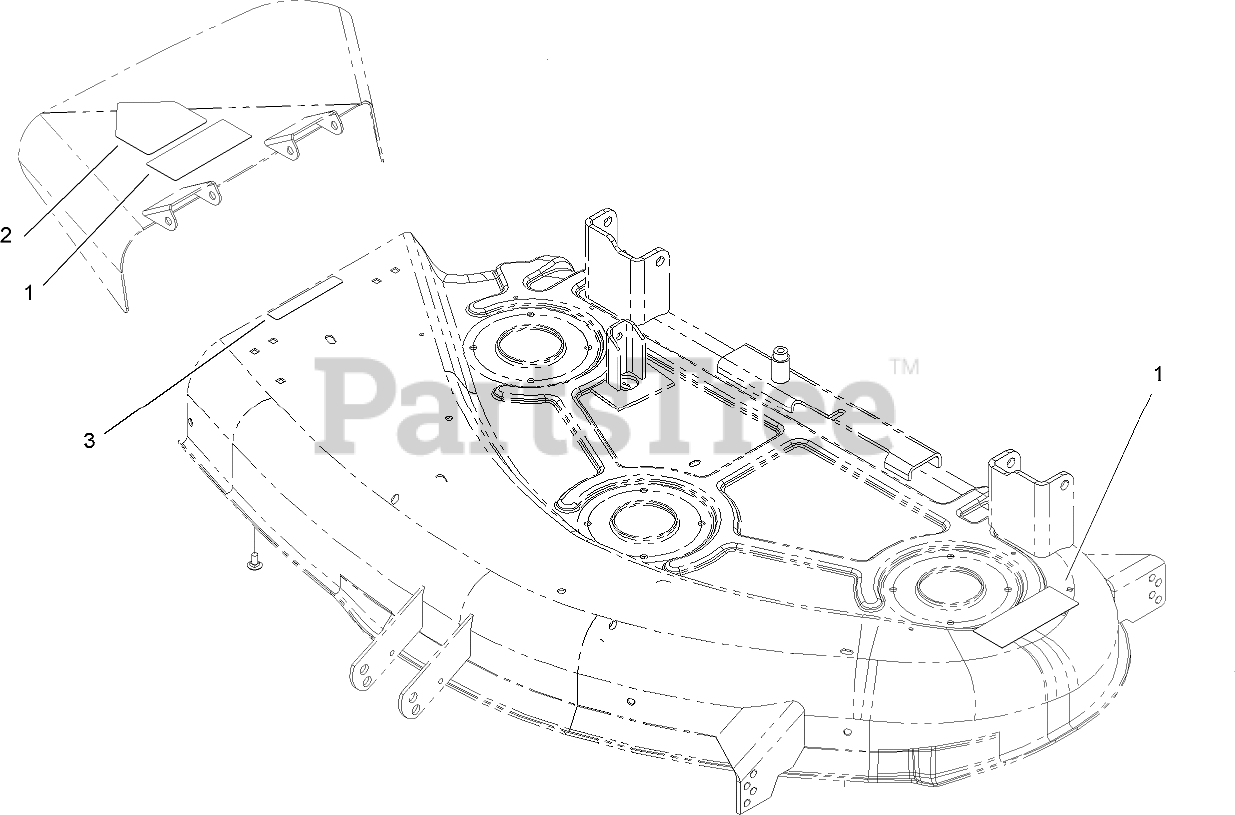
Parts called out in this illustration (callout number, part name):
1	DECAL-DANGER
2	DECAL-DANGER
3	DECAL-DANGER
